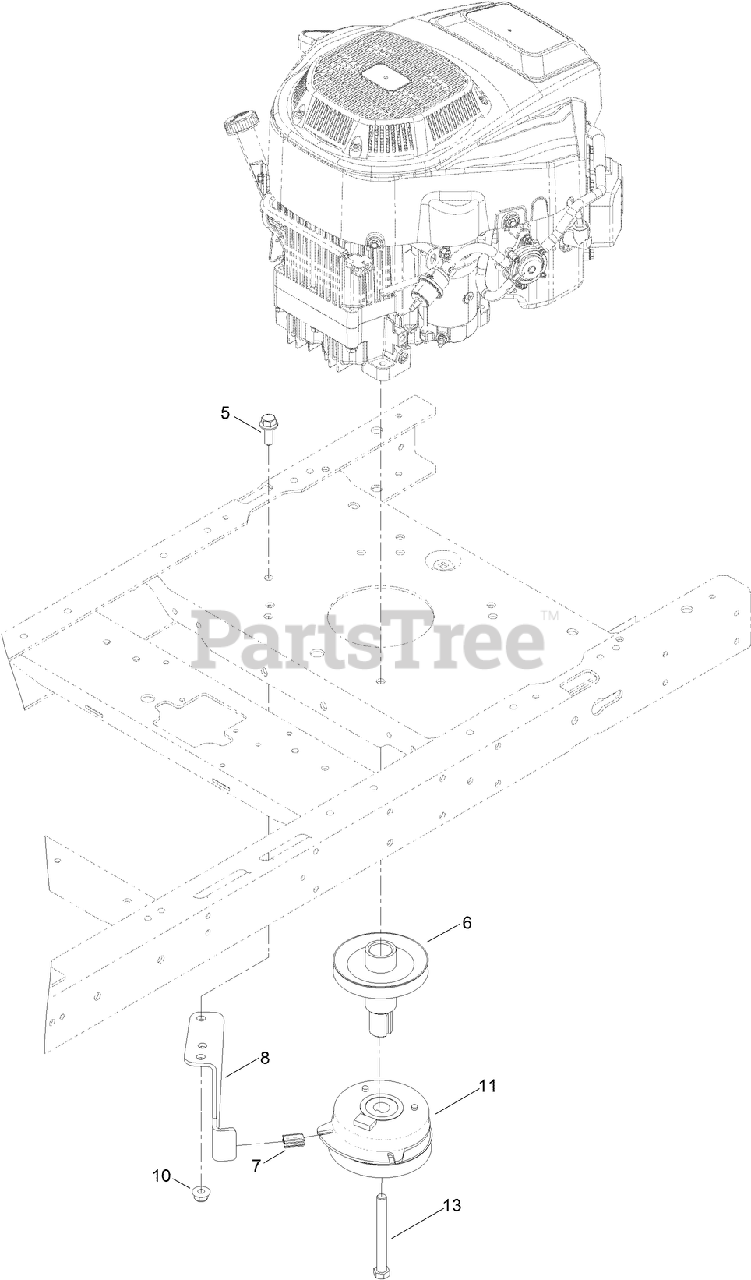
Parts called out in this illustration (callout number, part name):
5	SCREW-HHF
6	PULLEY-ENGINE
7	ISOLATOR-CLUTCH
8	STOP-CLUTCH
10	NUT-HF, NI
11	CLUTCH-PTO
13	SCREW-HH
